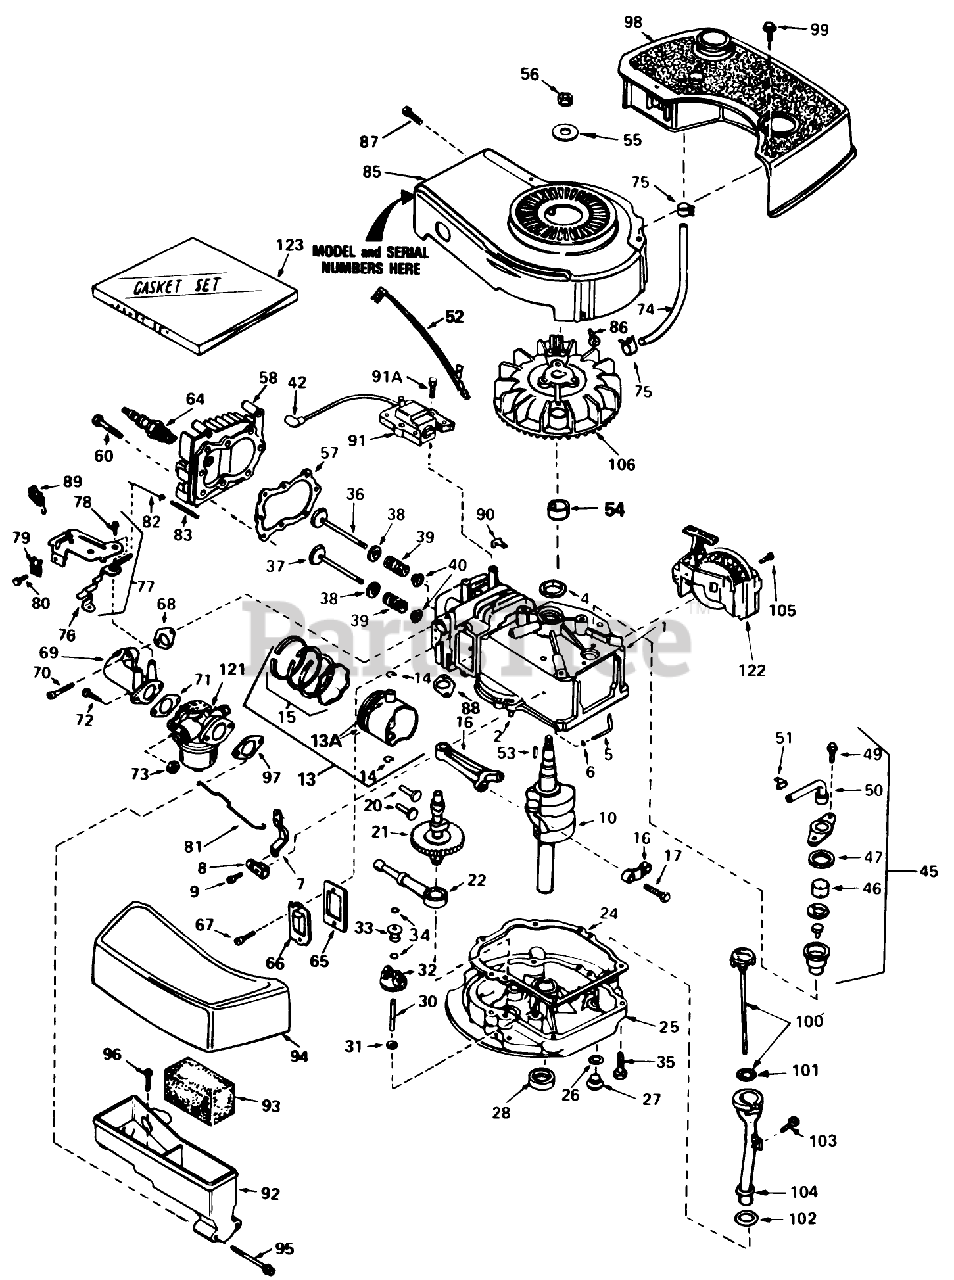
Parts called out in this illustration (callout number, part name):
1	Cyiinder Assy. (Incl. Ref. #2, 4 105)
2	Pin-Dowel
4	Seal-Oil
5	Rod, Governor (Incl. No. 36)
6	Washer-Flat
7	Governor Lever
8	Clamp-Lever, Governor
9	Screw
10	Crankshaft
13	Piston, Pin Ring Assy. (Std.) (Incl. Ref. #13A, 14 15)
13	Piston, Pin Ring Assy. (.010 oversize) (Incl. Ref. #13A, 14 15)
13	Piston, Pin Ring Assy. (.020 oversize) (Incl. Ref. #13A, 14 15)
13A	Piston Pin Assy. (Incl . Ref. . #14) (Std.)
13A	Piston Pin Assy. (Incl. Ref. #14) (.010 Oversize)
13A	Piston Pin Assy. (.020 oversize) (Incl. Ref. #14)
14	Ring-Retaining, Piston Pin
15	Ring Set (Std.)
15	Ring Set (.020" OS)
15	Ring Set (.010" OS)
16	Rod Assy., Connecting (Incl. Ref. #17)
17	Bolt-Rod, Connecting
20	Lifter-Valve
21	Camshaft(Mech.Comp. Release)
22	Oil Pump ASM
24	Gasket, Mounting
25	Flange Assy., Mounting (Incl. Ref. #26thru 30)
26	Gasket-Oil Drain
27	Plug Oil Drain
28	Seal Oil
30	Shaft-Governor
31	Washer-Flat
32	Governor Gear ASM
33	Spool-Governor
34	Ring-Retaining
35	Screw (1/4-20 x 1-1/4)
36	Valve, Intake (Std.) (Incl. Ref. #40)
36	Valve, Intake (1/32" oversize)(Incl. No. 40)
37	Valve, Exhaust (Std.)(Incl. No. 40)
37	Valve, Intake (1/32" oversize)(Incl. No. 40)
38	Cap-Upper Valve Spring
39	Spring-Valve
40	Cap-Valve, Spring
42	Cover-Spark Plug
45	Breather Assy. (Incl. Ref. #46 thru 51)
46	Element-Breather
47	Gasket-Breather
49	Screw (10-24 x 9/16)
50	Tube, Breaker
51	Clip, Breather
52	Wire-Ground
53	Key-Flywheel
54	Spacer
55	Washer-Belleville
56	Nut-Flywheel
57	63573 GIL 42 SNWTHW
58	Head-Cylinder
60	Screw (5/16-18x1-1/2)
64	Plug, Spark (J17LM or equiv.)
64	Plug, Spark (Champion RCJ-8)
65	Gasket-Breather
66	Cover-Valve
67	Screw
68	Gasket-Intake
69	Pipe, Intake (Incl. No. 68)
70	Screw (1/4-20 x 1)
71	Gasket-Carburetor
73	Nut and Lock Washer (1/4-28)
74	Line-Fuel
75	Clamp-Line, Fuel
76	Lever Control
77	Control Assy., Speed (Incl. Nos, 76, 78 89)
78	Screw, Hex Washer Hd Shoulder Self-Tap
79	Conduit
80	Screw (10-32 x 3/8)
81	Link-Throttle
82	Link Governor Spring
83	Spring Governor
85	Housing-Blower
86	Screw (1/4-20x19/32)
87	Screw (10-24 x 9/16)
88	Gasket Exhaust
89	Terminal
90	Clip-Wire
91	Solid State
91A	Screw
92	Body Air Cleaner
93	Filer, Air
94	Cove, Air Cleaner
95	Screw Fil Hd.
96	Screw, Hex Hd.
97	Gasket-Air Cleaner
98	Tank-Fuel
99	Screw (10-32 x 35/64)
100	Dipstick, Oil (Incl. Ref. #101)(Twist Lock)
101	O-Ring
102	Gasket
103	Screw (10-32 x 1/2)
104	Tube-Oil Fill
105	Screw (1/2-20x5/8)
106	Flywheel
121	Carburetor (Incl. Ref. #71)
122	Starter-Sidemount
123	Gasket Set
